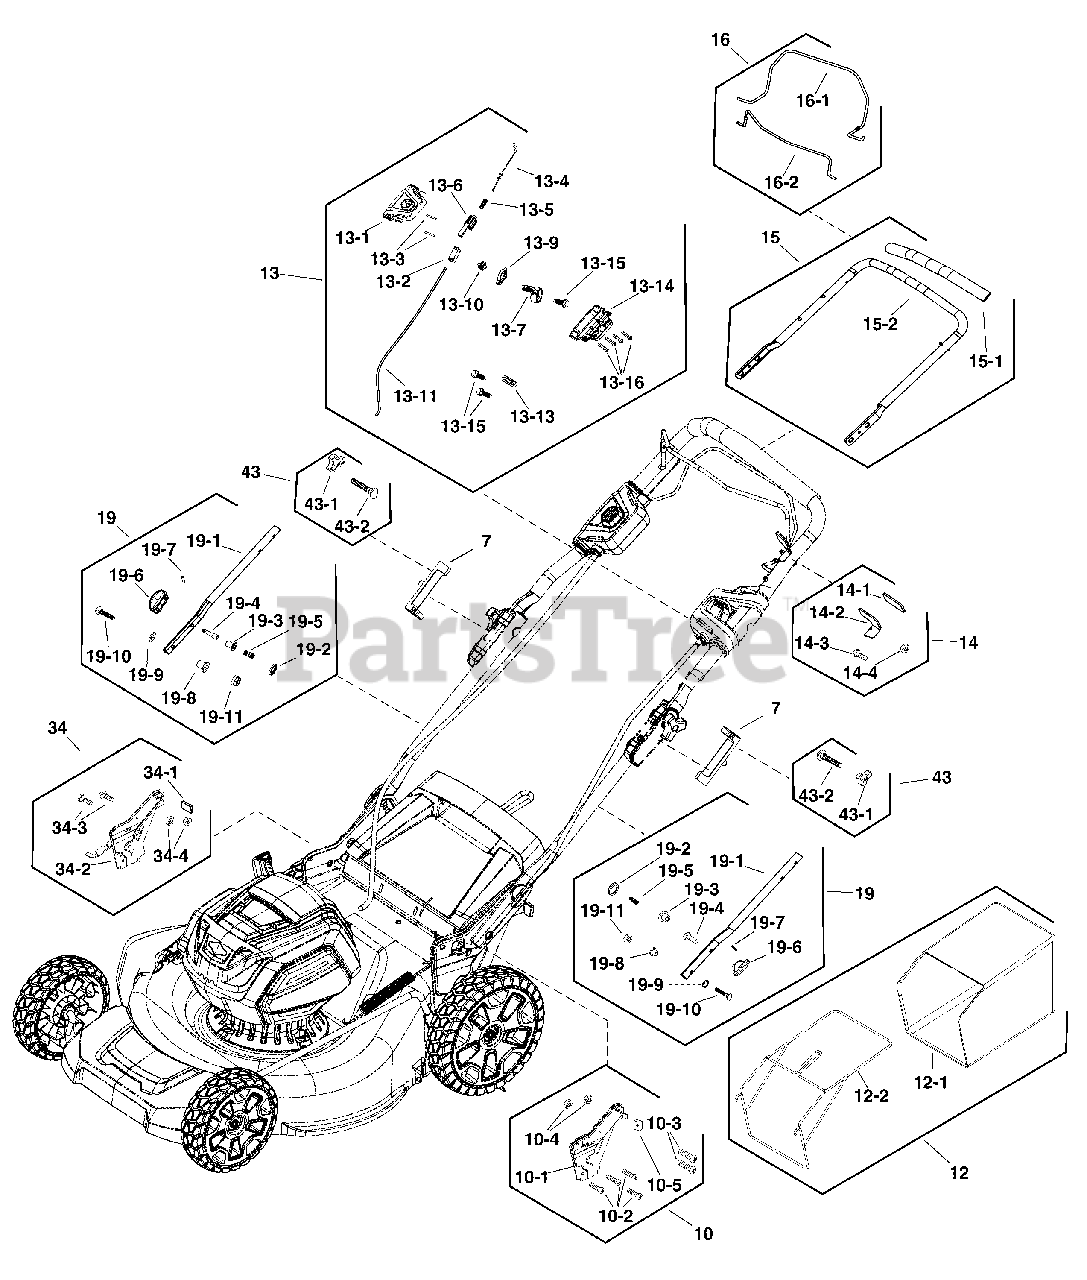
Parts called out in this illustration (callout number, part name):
7	KIT, SLEEVE
10	KIT, LEFT BRACKET
10-1	BRACKET, Height Adjust
10-3	BOLT
10-4	NUT
10-5	BUMPER
12	KIT, GRASS BAGGER
12-1	BAG, Grass Catcher
12-2	FRAME
13	KIT, VARIABLE SPEED CONTROL
13-1	MICROSWITCH
13-3	PIN. ROLL
13-4	CABLE, Bail
13-5	SPRING
13-6	SLIDER
13-7	KIT, Speed Control
13-9	SELF-PROPEL GEAR, BIG
13-10	SELF-PROPEL GEAR, SMALL
13-11	HARNESS, SPEED CONTROL
13-13	CLAMP
13-14	BOTTOM COVER
14	KIT, STOP
14-1	SPONGE
14-2	STOP
14-3	BOLT
14-4	NUT
15	KIT, UPPER HANDLE
15-1	HANDLE, UPPER
15-2	FOAM GRIP
16	KIT, BAIL & SPEED CONTROL
16-1	SPEED CONTROL LEVER
16-2	BAIL LEVER
19	KIT, LOWER HANDLE
19-1	LOWER HANDLE
19-2	GASKET
19-3	INSERT
19-4	POST
19-5	SPRING
19-6	KNOB
19-7	PIN
19-8	BLOCK
19-9	WASHER, Flat
19-10	BOLT
34	KIT, RIGHT BRACKET
34-1	BUMPER
34-2	RIGHT HEIGHT ADJUST
34-3	BOLT
34-4	NUT
43	KIT, HARDWARE
43-2	BOLT
